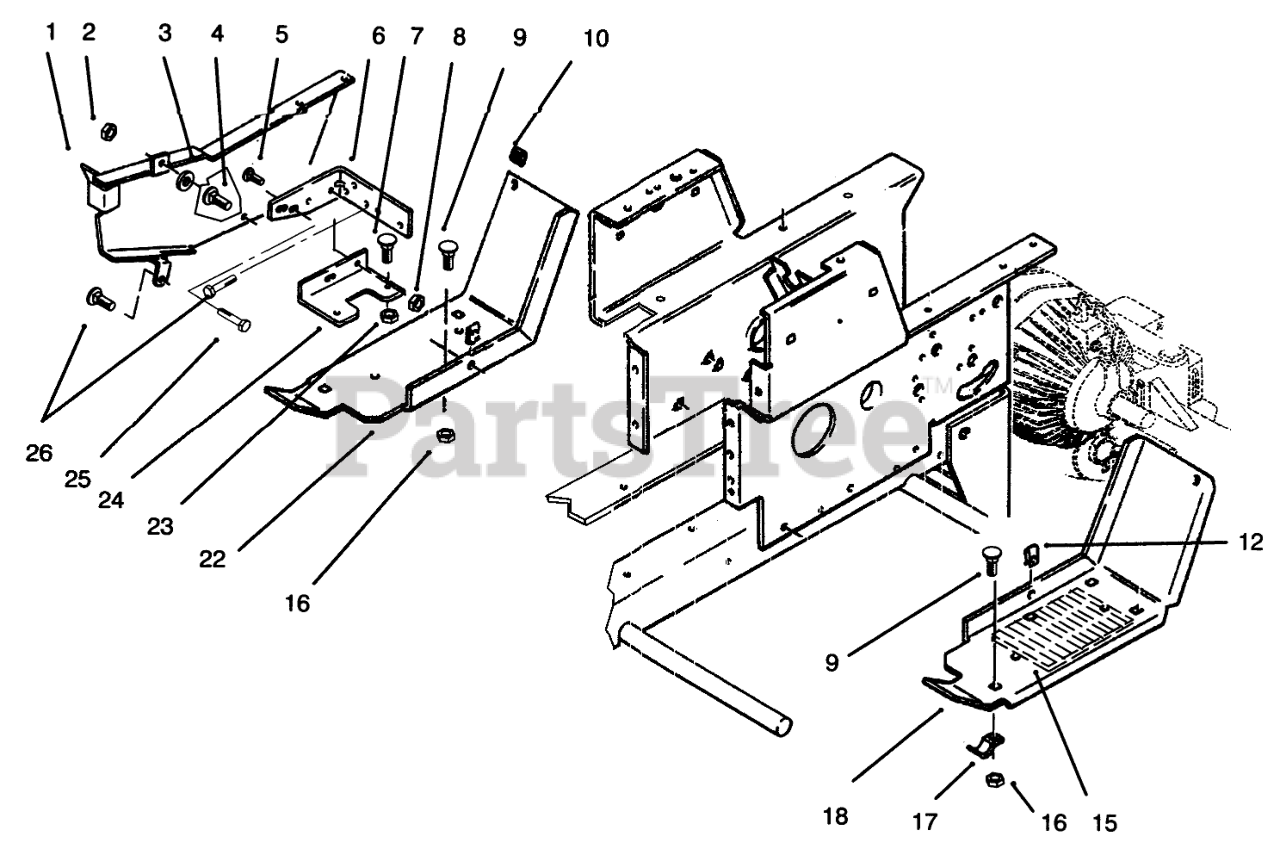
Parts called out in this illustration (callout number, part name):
1	GUARD - BELT WA R
2	NUT-LOCK, NI
3	NUT-PUSH
4	SCREW-PPH
5	SCREW-HH
6	BRACKET-BELTB
7	SCREW-PAN
8	NUT-LOCK, NI
9	BOLT-CARR
10	BUMPER
15	PAD FOOTREST
16	NUT-LOCK, NI
17	BRACKET
18	FOOTREST LH R
22	Footrest-RH
23	Nut
24	BRKT-FUS HLDERB
25	BOLT-CARR
26	Bolt
